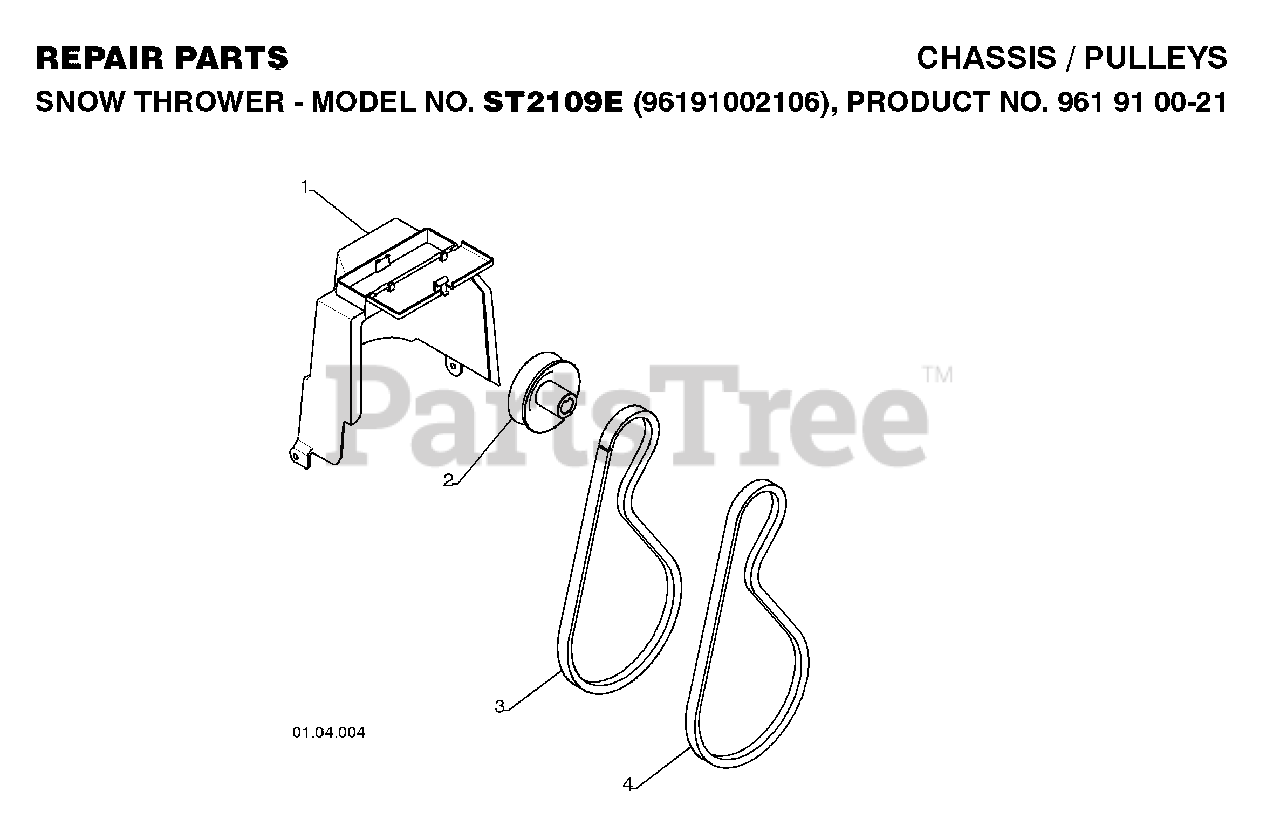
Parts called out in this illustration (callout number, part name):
1	COVER.BELT.HS
2	PULLEY
3	V-BELT.TRACTION
4	BELT-V.IMPELLER.HS
